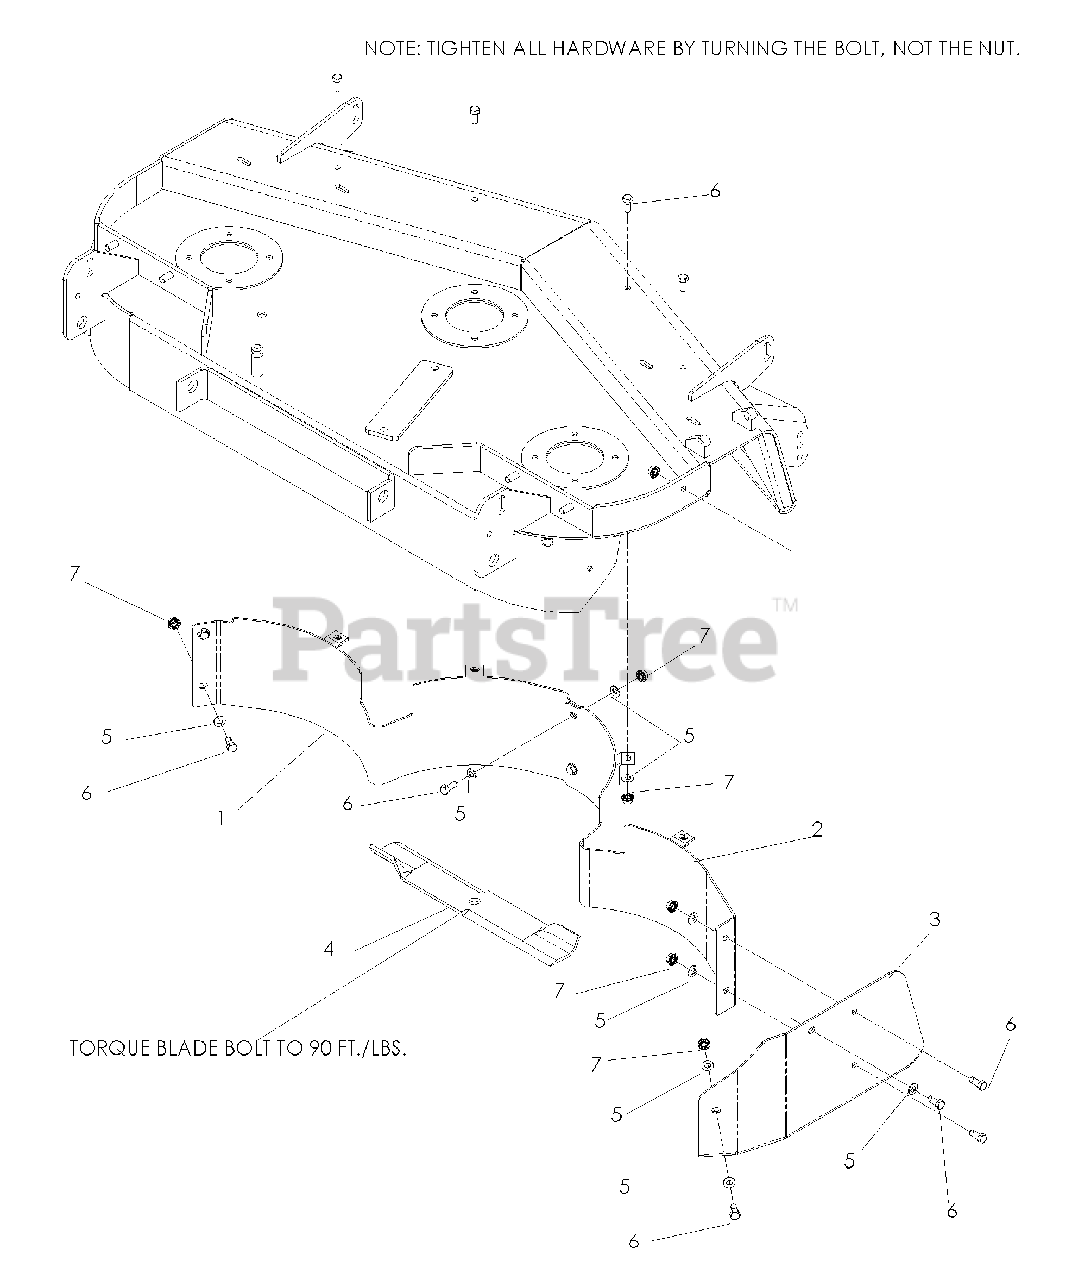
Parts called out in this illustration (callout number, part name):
1	BAFFLE, LT
2	BAFFLE, RT
4	MULCH BLADE, 21"
5	WASHER 5/16 FLAT SAE
6	HCS 5/16-18 x 3/4
7	NUT 5/16-18 WHIZ
